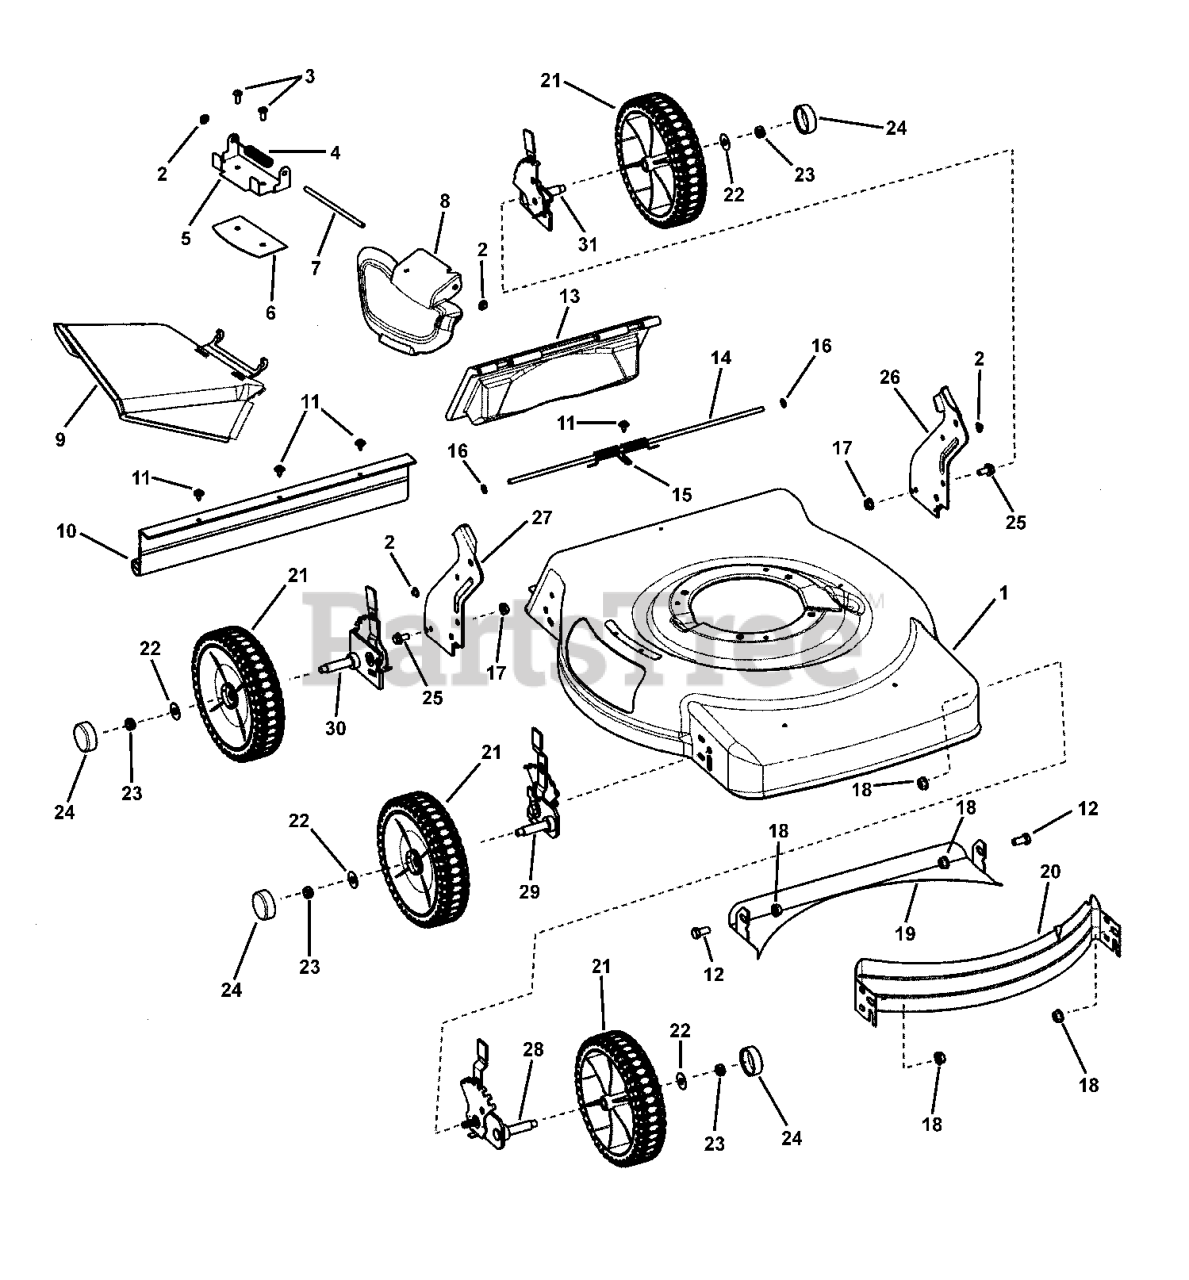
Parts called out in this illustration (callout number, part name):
1	DECK, 22" Walk, Push 3-N-1
2	PUSHNUT, 1/4"
3	SCREW, 1/4-20 x 11/16" Pan Head Self-Tap (Torx)
4	SPRING, Torsion, Chute
5	BRACKET, Chute
6	PLATE, Mulch 22" RB Scotts
7	ROD, Chute Pivot - 1/4" dia. x 5.55"
8	COVER, Mulch, Plastic, Black
9	SIDE CHUTE, Plastic, Black
10	GUARD, Rear
11	SCREW, #10-24 x 1/2" Hex Washer Self-Tap - Sems
12	SCREW, 3/8-16 x 3/4" Hex Head Cap, GR 5
13	DOOR, Rear Discharge, 22" Walk Mower
14	ROD, Pivot, Rear Door - 1/4" dia. x 17-1/2"
15	SPRING, Torsion, Rear Door, 22" Walk Mower
16	CAP, Retainer (for 1/4" rod)
17	NUT, 5/16-18 Hex Flange Lock BZ
18	NUT, 3/8-16, Hex Flange Lock, GR 5
19	BAFFLE, Rear, 22" Deck
20	BAFFLE, Front, 22" Walk Mower
21	WHEEL, 8" x 2" Idle, w/Db Tread, Brute Yellow
22	WASHER, Flat, 1" O.D. x .387 I.D.
23	NUT, 3/8-16 Hex Center Lock YZ
24	HUBCAP, Round, Black
25	BOLT, 5/16-18 x 5/8" Hex Flange Lock
26	BRACKET, Lower Handle, RH
27	BRACKET, Lower Handle, LH
28	ASSY, HOC, Left Front, 7 Position
29	ASSY, HOC, Right Front, 7 Position
30	ASSY, HOC, Right Rear, 7 Position
31	ASSY, HOC, Left Rear, 7 Position
